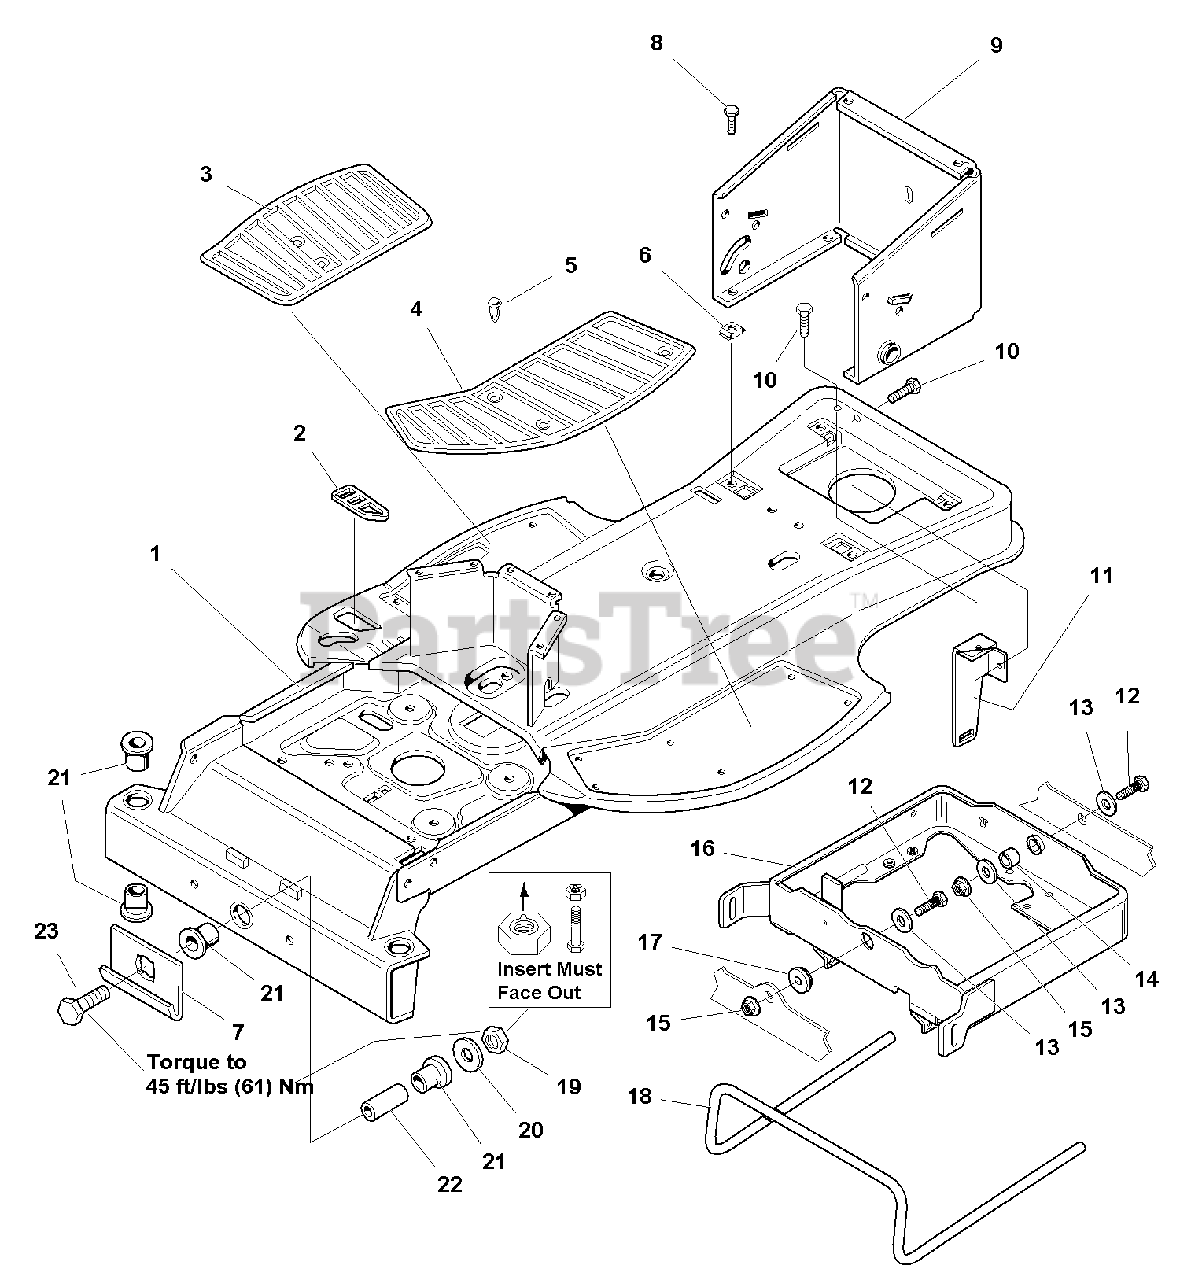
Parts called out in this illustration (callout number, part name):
1	FRAME ASSEMBLY
3	PAD, Footrest RH
4	PAD, Footrest LH
5	FASTENER, Panel
6	NUT, Speed 5/16-18
7	"J" HOOK, Hitch
8	SCREW, Hex Head Flange Lock, 5/16-18 x 3/4
9	WRAPPER ASSEMBLY
10	CAPSCREW, Hex Head Flange Whiz Lock, 5/16-18 x 3/4
12	CAPSCREW, Hex Head, 1/2-13 x 1/2
13	WASHER
15	NUT, Hex Head, 1/2-13
16	CARRIER ASSEMBLY
18	BAR, Torsion
19	NUT, Hex Head Aluninum Insert, 3/8-16
20	WASHER
23	CAPSCREW, Hex Head, 3/8-16 x 3, G8
